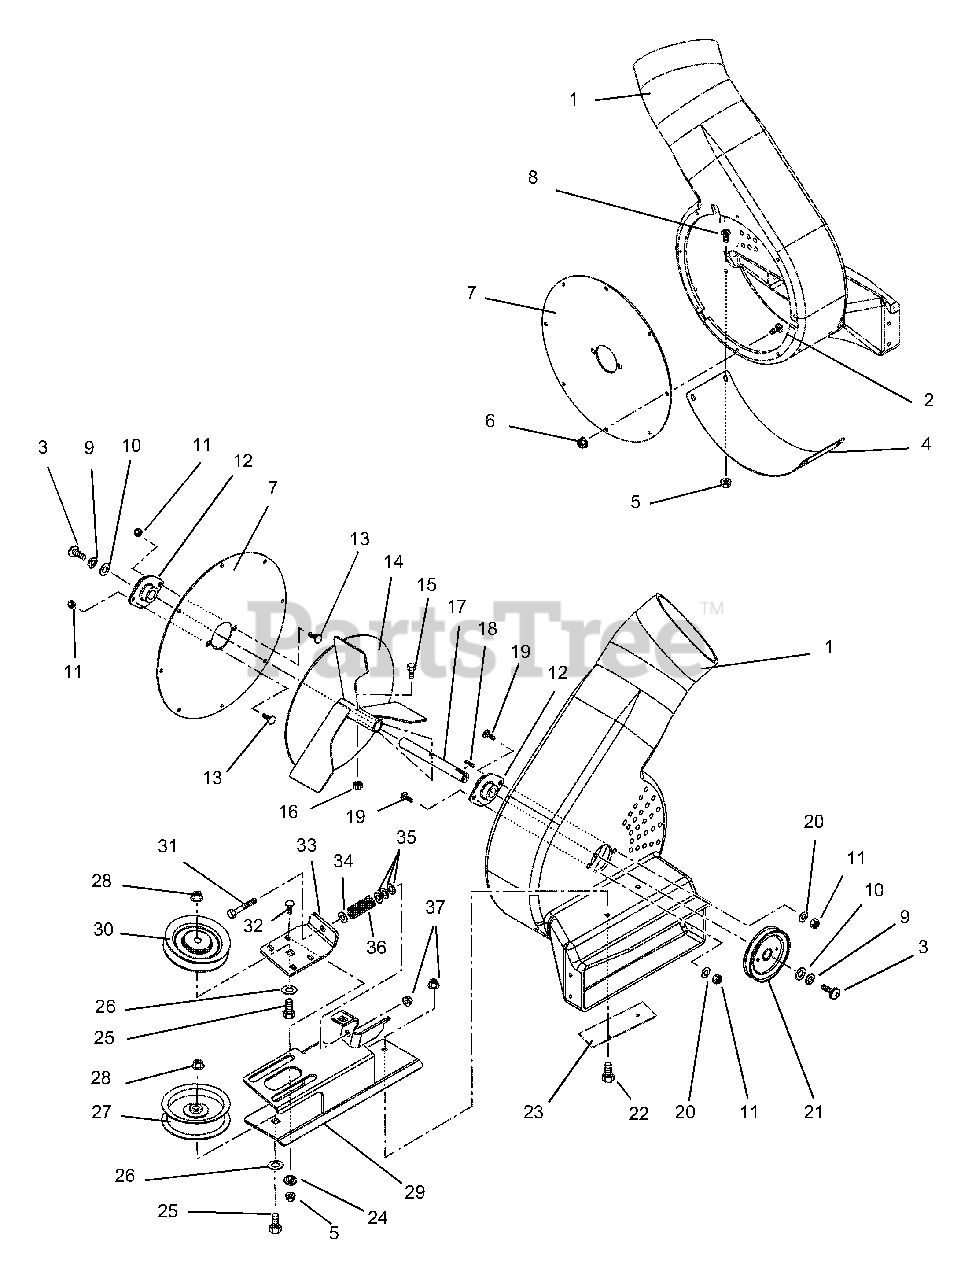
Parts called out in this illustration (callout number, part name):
1	Housing, Blower
2	Screw-Machine .25-20 x .63
3	Screw-Machine .25-20 x .75
4	Plate, Skid
5	Nut-Locking-Top-Flange .25-20
6	Nut-Locking-Flange .250-20
7	Plate, Bearing Mount
8	Screw-Machine .25-20 x .50
9	Washer-Locking .25 x .062 Regular
10	Washer-Flat-Steel .344 x 1.125 x .135
11	Nut-Locking-Nylon .312-18
12	Bearing, 2 Bolt Flange - .75 ID
13	Bolt-Round Head Square Neck .31-18X.62
14	Weldment, Impeller, 3 Blade
15	Bolt-Hex .25-20 x 1.50 Grade 5
16	Nut-Locking-Nylon .250-20
17	Shaft, Impeller
18	Key-Square .187 x .50 x .187 Hardened
19	Bolt-Round Head Square Neck .31-18 x .88 Grade 5
20	Washer-Flat-Steel .312 x .734 x .065
21	Sheave, Blower- 4.25 Diameter
22	Bolt-Hex .31-18 x .875 Grade 5
23	Plate, Back
24	Bushing-Flange .265 x .437 x .250 x .750
25	Bolt-Hex .38-16 x 1.75 Grade 5
26	Washer-Flat-Steel .406 x .812 x .065
27	Idler Flanged 3.50
28	Nut-Locking-Top-Flange .38-16
29	Weldment, Idler Mount
30	V-Idler, 4.00 x .38
31	Bolt-Hex .31-18 x 4.00 Grade 5
32	Bolt-Round Head Square Neck .25-20 x .75 Grade 5
33	Bracket, Adjustable Idler
34	Nut-Push .312
35	Washer-Flat-Steel .406 x 1.00 x .188
36	Spring-Compression .092 x .77 x 3.13
37	Nut-Locking-Top-Flange .31-18
38	Blower, Service Assembly
